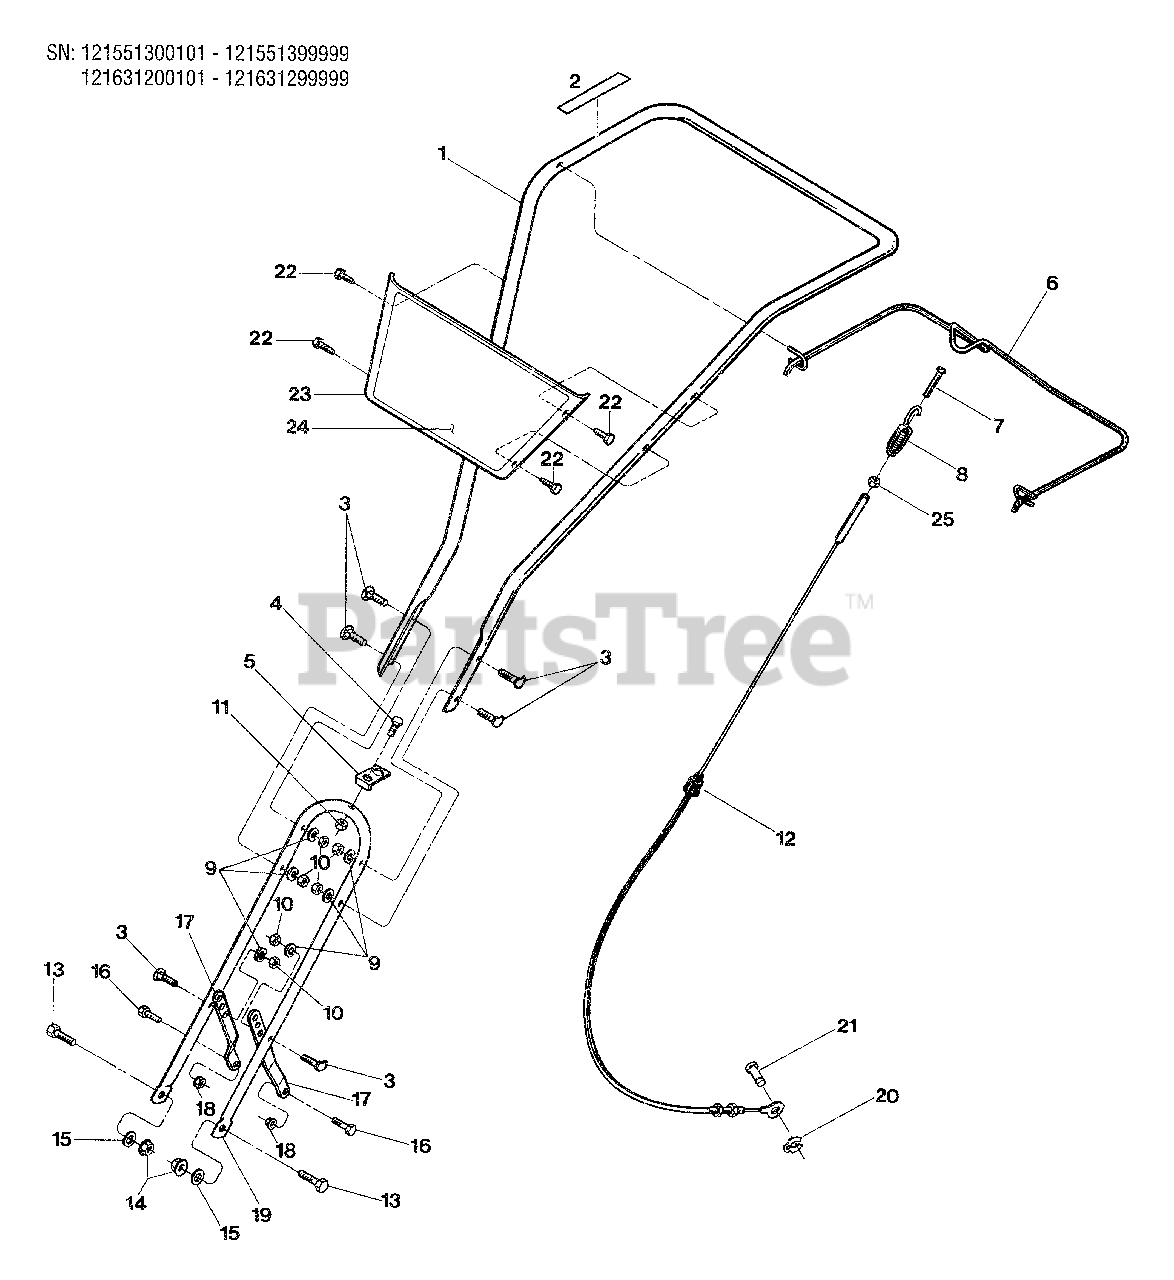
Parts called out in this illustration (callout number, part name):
1	Handlebar, Upper
2	Decal-Forward Clutch Bail
3	Bolt-Curved Hd., 5/16-18 x 1-1/2
4	Bolt-Hex Hd., 1/4-20 x 1-1/4
5	Bracket, Cable
6	Bail-Forward Clutch
7	Screw, #10-24 x 2
8	Spring-Forward Clutch
9	Lockwasher-5/16
10	Nut-Hex Hd., 5/16-18
11	Nut-Hex Hd., Lock, 1/4-20
12	Cable Assy-Forward Clutch
13	Bolt-Hex Hd., 3/8-16 x 3/4
14	Locknut-Hex Hd., 3/8-16
15	Washer-Flat, 318
16	Bolt-Hex Hd., 5/16-18 x 3/4
17	Support, Handlebar
18	Locknut-Hex Hd., 5/16-18
19	Handlebar, Lower
20	Klip Ring
21	Clevis Pin
22	Screw-Hex Hd., 1/4-20 x 1/2, Self-Tapping
23	Panel
24	Decal-Model Name/Logo
25	Nut-Hex Hd., #10-24
